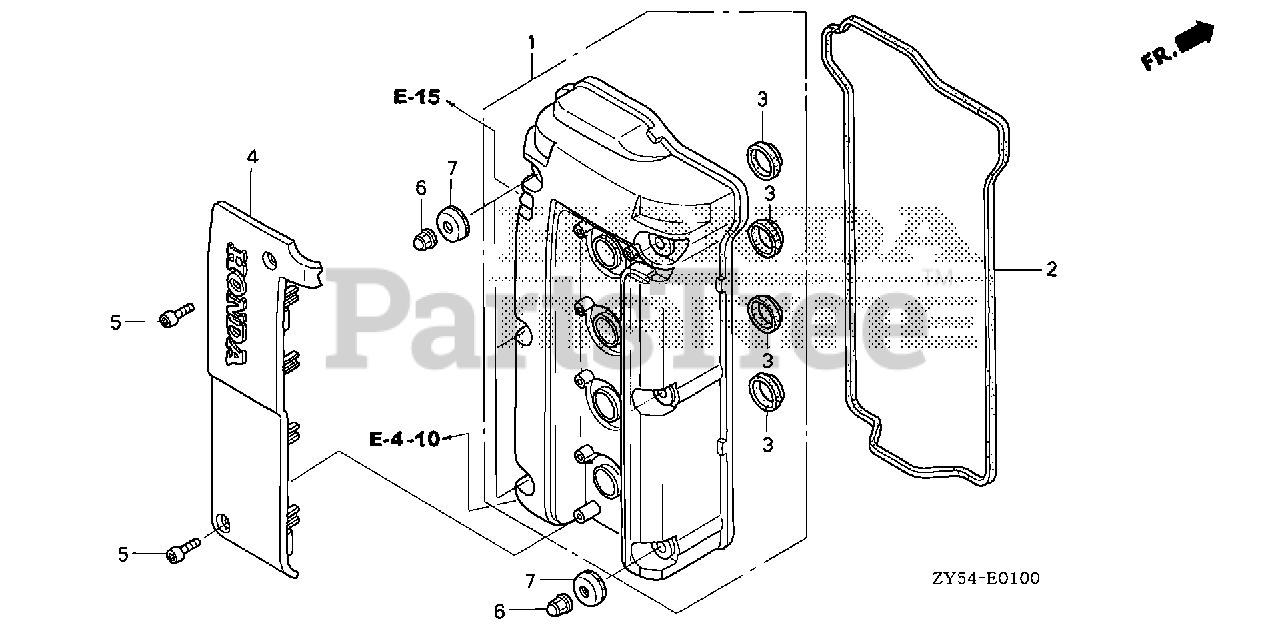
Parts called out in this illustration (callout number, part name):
1	COVER, CYLINDER HEAD *NH8* (DARK GRAY)
1	COVER, CYLINDER HEAD *NH8* (DARK GRAY) (FOR 14540-RWC-A02)
2	GASKET, CYLINDER HEAD COVER
3	SEAL, SPARK PLUG TUBE (NOK)
4	COVER, PLUG HOLE COIL
5	BOLT, SOCKET (6X25)
6	NUT, FLANGE CAP (6MM)
7	WASHER, HEAD COVER
